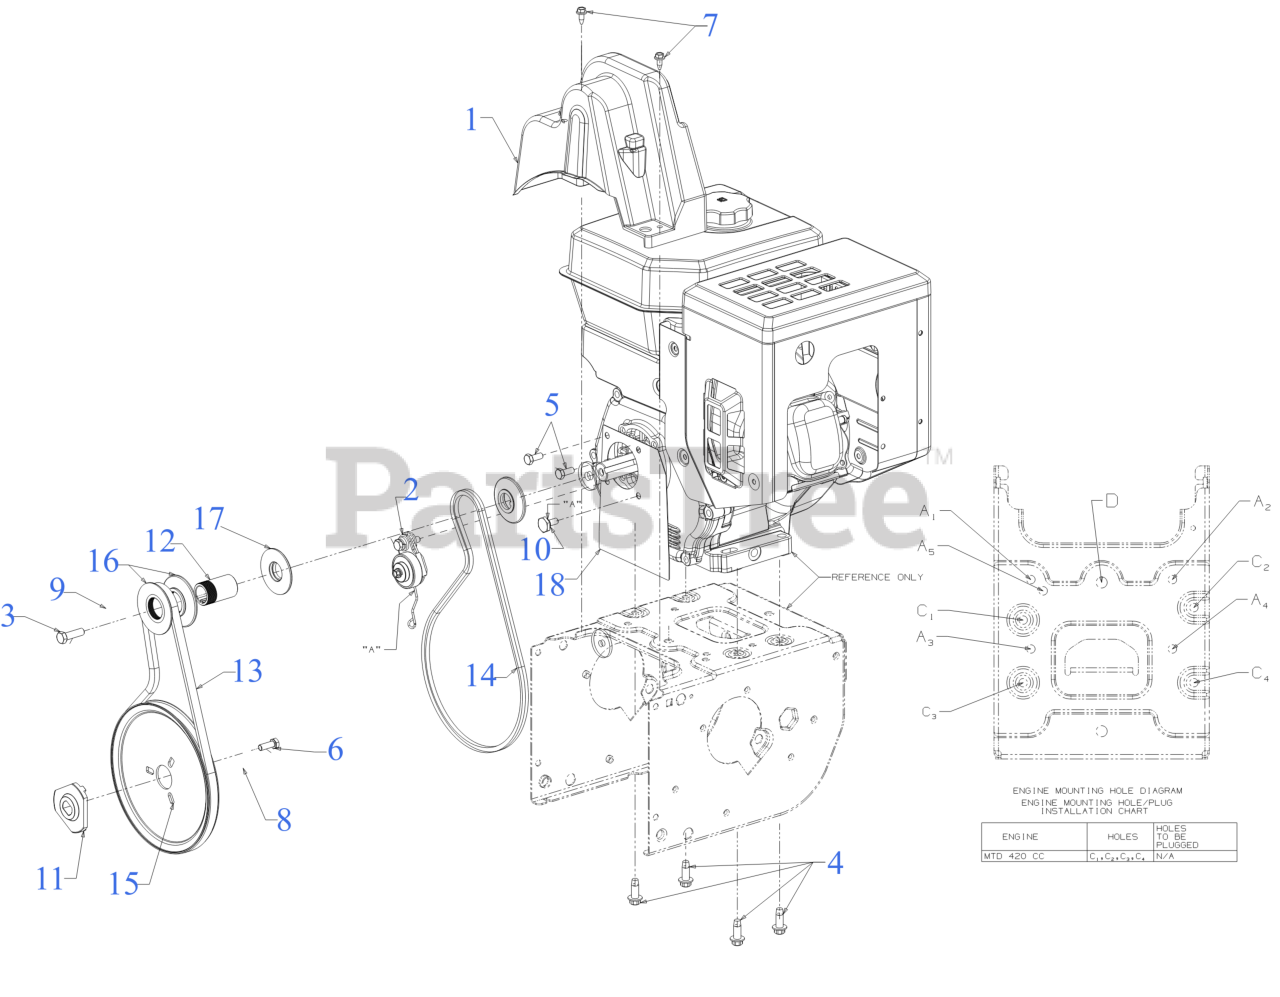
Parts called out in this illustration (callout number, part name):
1	BELT COVER SERVICE KIT (631-05323)
1	HEX SCREW #12-16 x .50
2	IDLER ASSEMBLY
3	SCREW 3/8-24X1.25
4	SCREW 3/8-16 x 1
5	SCREW 5/16-24 x .750 GR5
6	SCREW 5/16-24 x .875 GR5
7	SCREW 1/4-20X.625
8	FLAT WASHER
9	FLAT WASHER .45 x 1.5 x .172 HT
10	SHOULDER SCREW
11	ADAPTER PULLEY .75 DIA W/DD
12	PULLEY SPACER
13	BELT-.500 x 37.00
14	BELT-3L x 36.64 LG
15	AUGER PULLEY
16	HALF PULLEY 4L V x 2.6 OD
17	HALF PULLEY 3/8-V x 2.2
18	ENGINE PLATE (FRONT COVER)
